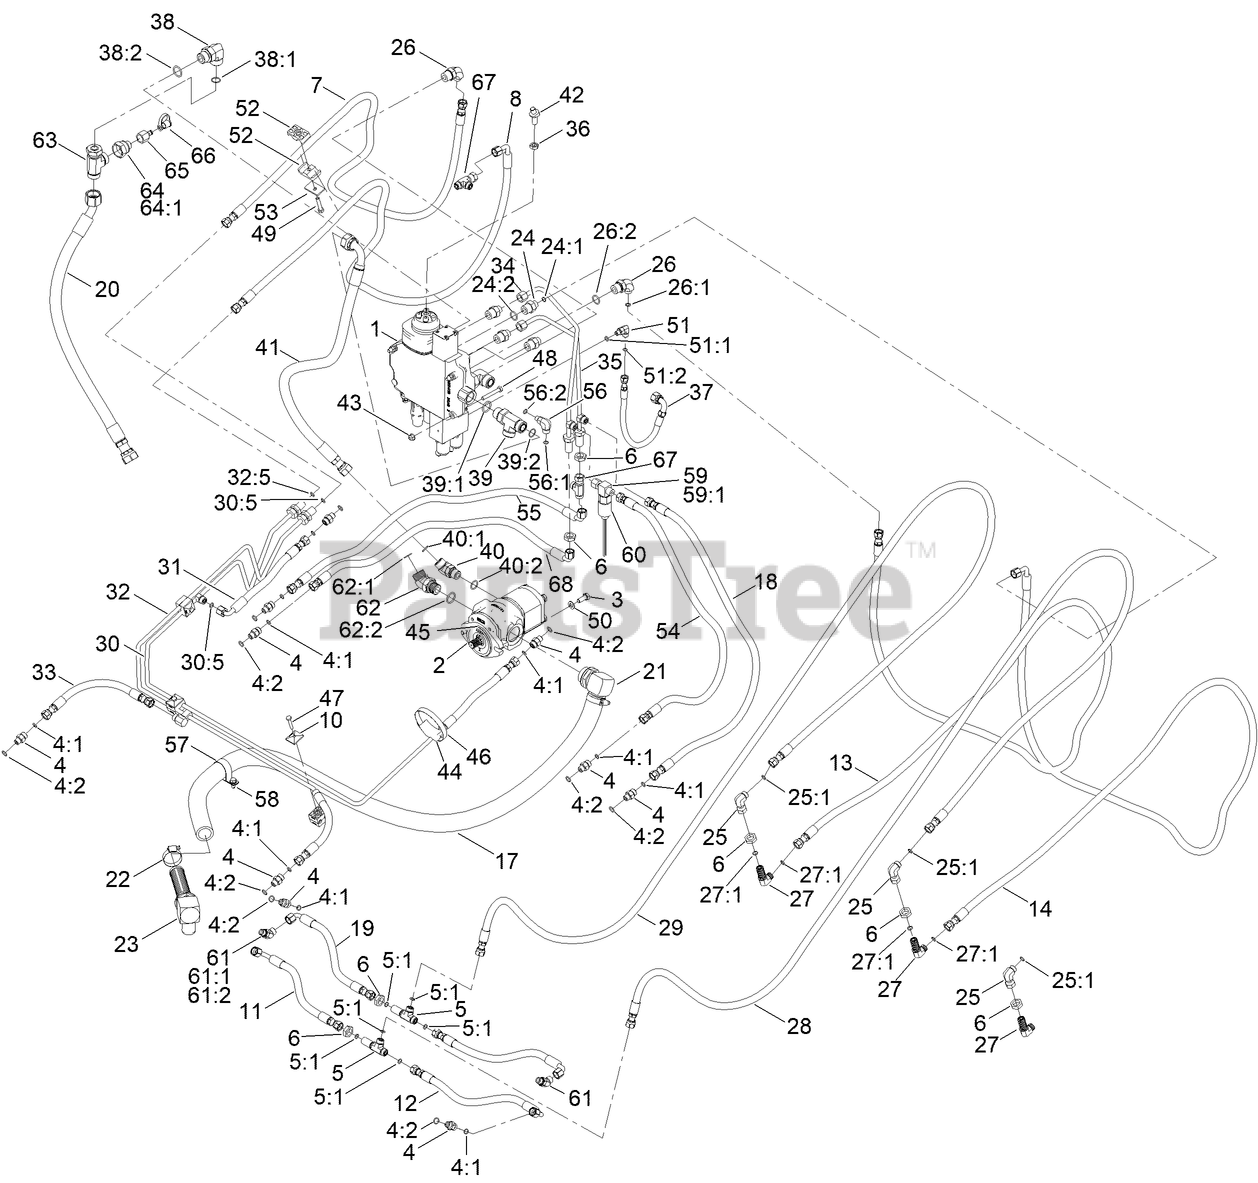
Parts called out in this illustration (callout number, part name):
1	LIFT VALVE ASM
2	GEAR PUMP ASM
3	SCREW-HH
4	FITTING-STRAIGHT
4:1	O-RING
4:2	O-RING
5	FITTING-TEE, BULKHEAD
5:1	O-RING
6	NUT-LOCK
7	HYD HOSE ASM
8	HYD HOSE ASM
10	PLATE-CLAMP, RETAINER
11	HYD HOSE ASM
12	HYD HOSE ASM
13	HYD HOSE ASM
14	HYD HOSE ASM
18	HYD HOSE ASM
19	HYD HOSE ASM
20	HYD HOSE ASM
21	FITTING-HYD 90 SPCL
23	STRAINER-SUCTION
24	FITTING-STR
24:1	O-RING
24:2	O-RING
25	FITTING-HYD, 90 DEG
25:1	O-RING
26	FITTING-ELBOW 90
26:1	O-RING
26:2	O-RING
27	UNION-BULKHEAD
27:1	O-RING
28	HYD HOSE ASM
29	HYD HOSE ASM
30	HYD TUBE ASM
30:5	O-RING
31	HYD HOSE ASM
32	HYD TUBE ASM
32:5	O-RING
33	HYD HOSE ASM
34	HYD TUBE ASM
35	HYD TUBE ASM
37	HYD HOSE ASM
38	FITTING-ELBOW-90
38:1	O-RING
38:2	O-RING
39	FITTING-TEE
39:1	O-RING
39:2	O-RING
40	FITTING-HYD, 45 DEG
40:1	O-RING
40:2	O-RING
41	HYD HOSE ASM
42	SHAFT-CONTROL
43	NUT-HF, NI
44	BLOCK-HARDLINE
45	O-RING
46	CLAMP-BAND/SCREW
47	SCREW-HH
48	SCREW-HH
49	SCREW-HH
50	WASHER-FLAT
51	FITTING-ELBOW, 90 DEG
51:1	O-RING
51:2	O-RING
52	CLAMP-TUBE
53	COVERPLATE
54	HYD HOSE ASM
55	HYD HOSE ASM
56	FITTING-ELBOW, 90 DEG
56:1	O-RING
56:2	O-RING
57	CLAMP-R
58	SCREW-HWH
59	FITTING-HYD, SPECIAL
59:1	O-RING
60	SWITCH-PRESSURE,
61	FITTING-ELBOW, 45 DEG
61:1	O-RING
61:2	O-RING
62	FITTING-45 DEG
62:1	O-RING
62:2	O-RING
63	FITTING-HYD
64	FITTING-STRAIGHT
64:1	O-RING
65	FITTING
66	CAP-DUST
67	FITTING-TEE, SWIVEL NUT
68	HYD HOSE ASM
